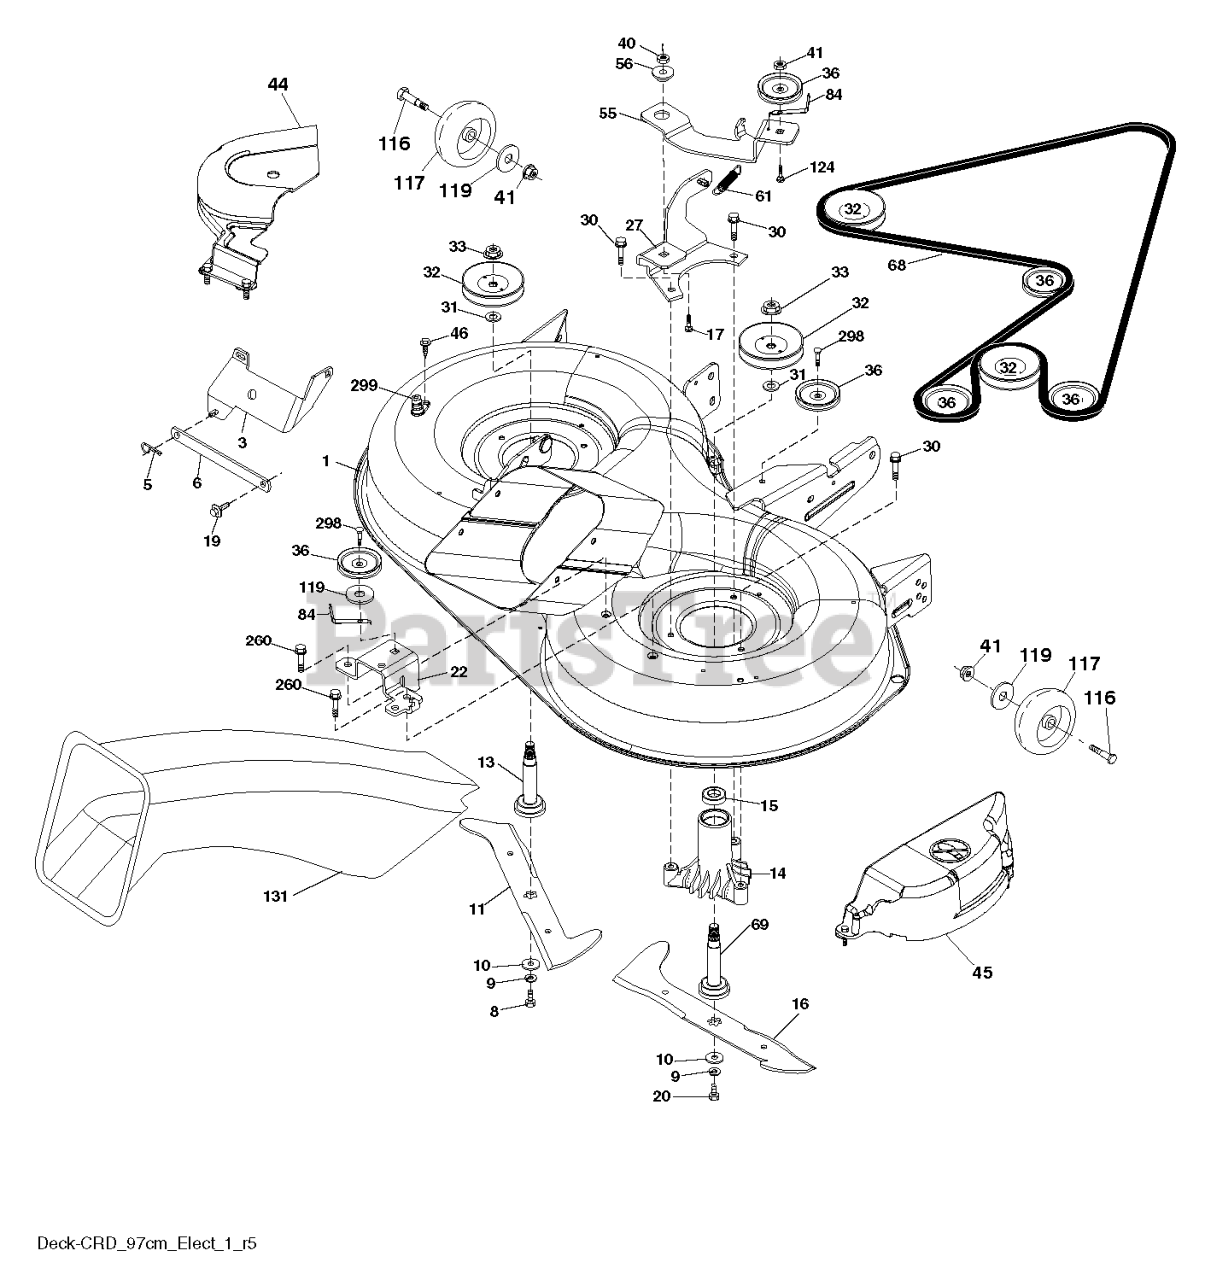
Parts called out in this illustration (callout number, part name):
1	DECK.WLDT.97.CRD.2GWB.
3	BRACKET.ASM.BAR.SWAY.CHASS
5	BRACKET.ASM.BAR.SWAY.CHASS
6	BAR.SWAY.92.CRD
8	BOLT.3/8-24X1.25 GR8
9	LOCKWASHER
10	WASHER.BLADE
11	BLADE.3N1.LH.CRD.97
13	SHAFT ASM VENT
14	HOUSING.MANDREL.VENTED (MACHD)
16	BLADE.3N1.RH.CRD.97
17	BOLT.3/8-14X1.25
19	BOLT SHD 5/16-18
20	BOLT.3/8-24X1.25GR8. LHTHRD
22	BRACKET.SUPT.IDLER.REAR.RH
27	BRACKET.ASM.SUSP.REAR.RH.
30	SCREW, WASHER HEAD
31	WASHER.SPACER.MANDREL
32	PULLEY MANDREL
33	NUT.FLANGE.LOCK.TOP
36	PULLEY.IDLER.4.25
41	NUT LOCK FLG 3/8-16 UNC
46	SCREW.1/4-20X5/8
55	ARM.IDLER.92 CRD.2006
56	SPACER.RETAINER.MOWER
61	SPRING
68	BELT.DRIVE.CRD.97.2010
69	SHAFT.ASM.W/LWR.BRG.RH.THREAD
84	KEEPER, BELT IDLER
116	BOLT.SHOULDER.3/8-16X3-5/8.
117	RP WHEEL. GUAGE RALLY
119	WASHER
124	BOLT.3/8-16X1.50
131	CHUTE BAGGER
260	SCREW 3/8-16X1/2
298	SCREW LT
299	PORT.WASHOUT
